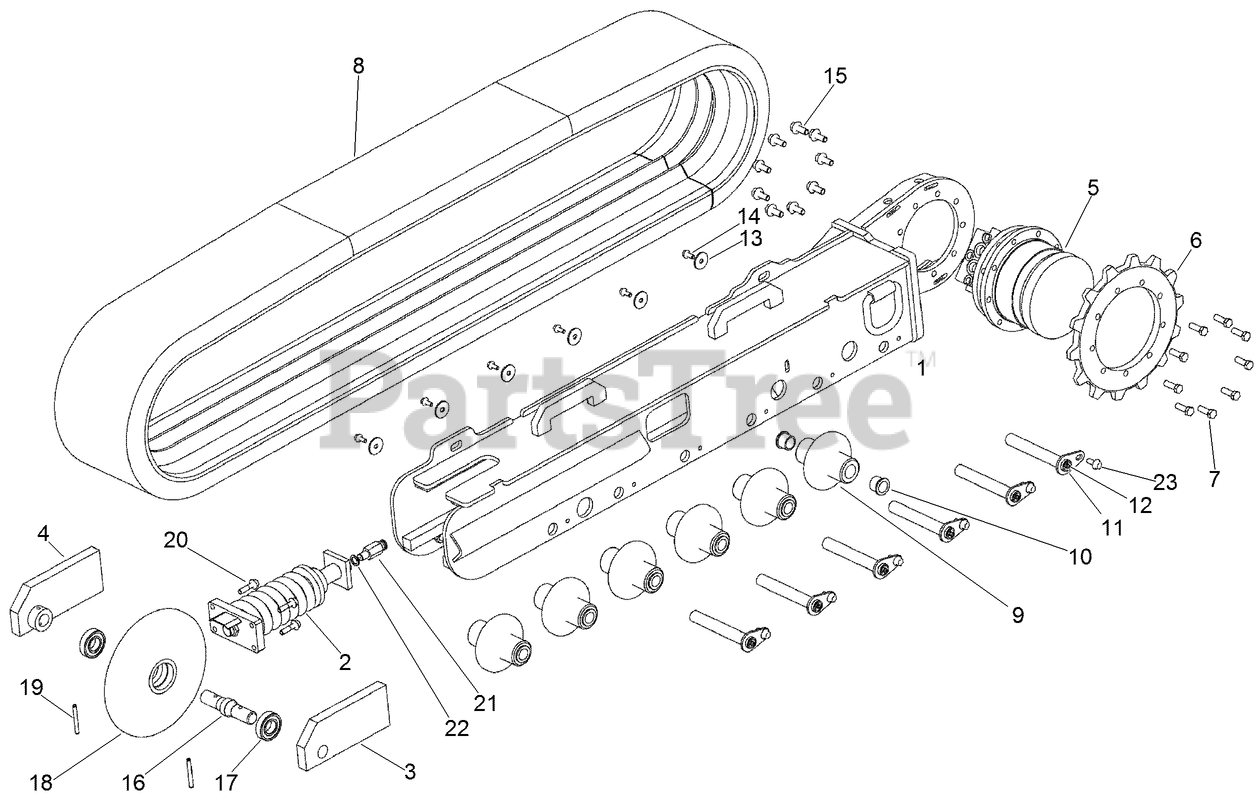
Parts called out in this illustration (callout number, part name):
1	WELDMENT - Track, RH
2	TENSIONER-TRACK, SPRING/GREASE
3	BRACKET - Idler, Right
4	BRACKET - Idler, Left
5	PLANETARY GEARBOX ASM
6	SPROCKET DRIVE
7	BOLT - Thd to Hd M12 x 35 CL8.8 ZND
8	TRACK-RUBBER
9	ROLLER - Track
10	BEARING-PLAIN, FLANGED
11	PIN-FLAG
12	FITTING-Lube 1/4-28 Tpr SAE-LT .54 Long
13	WASHER - .406 x 1.50 x .119 in CST ZND
14	SCREW, METRIC FLANGE w/BODY - M8 x 20
15	SCREW, METRIC FLANGE w/BODY-M12 x 30
16	PIN-MOUNT, IDLER
17	BEARING-BALL
18	WHEEL - Idler Track
19	PIN-SPRING
20	SCREW-FLANGE
21	VALVE-GREASE
22	SEAL-O RING
23	SCREW-FLANGE
